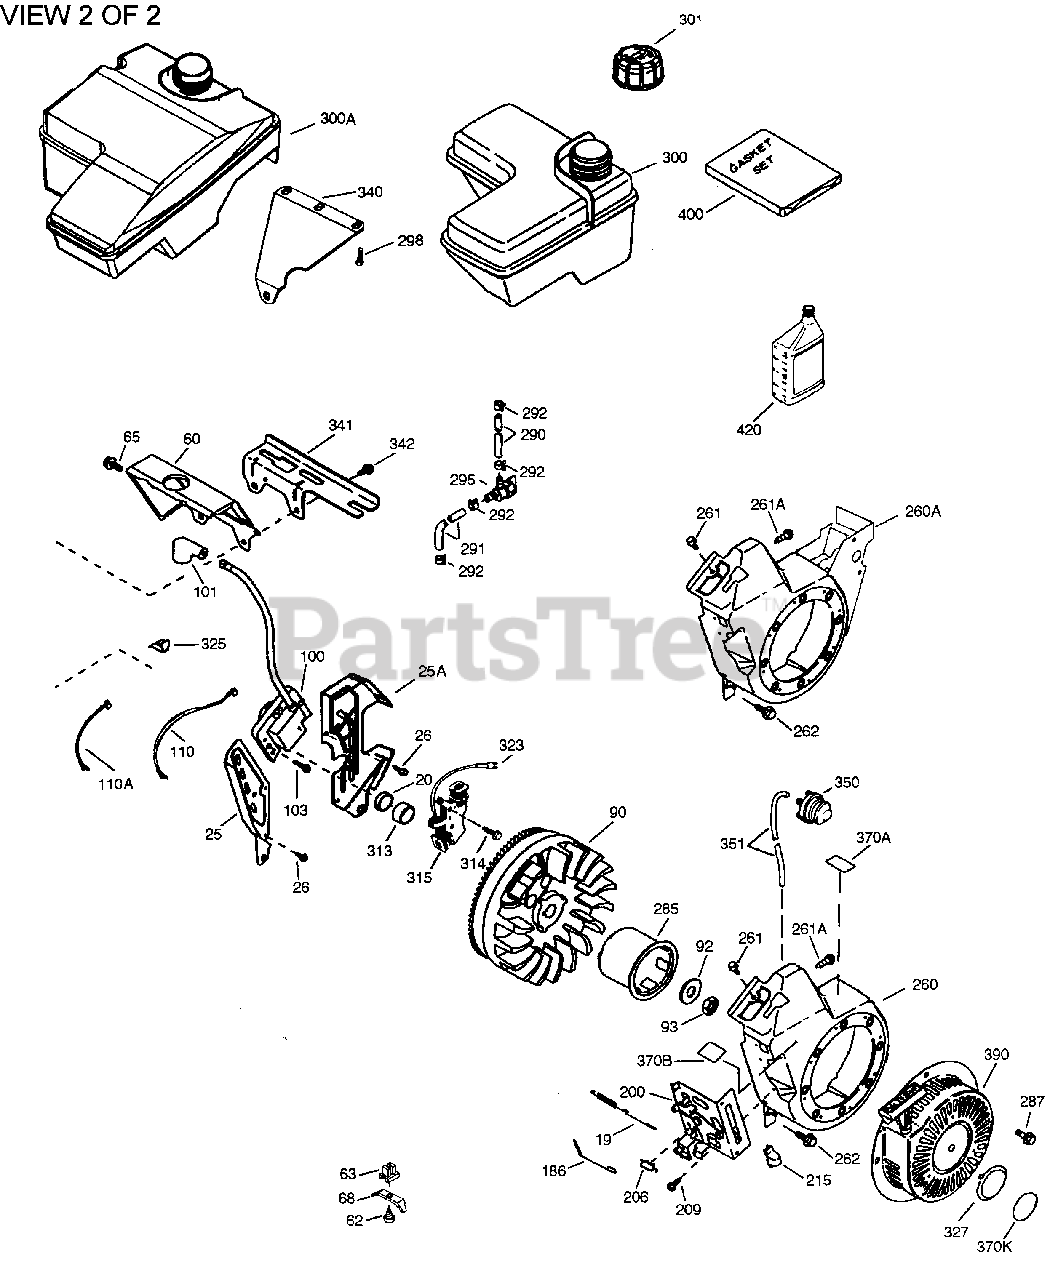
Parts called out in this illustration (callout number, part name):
19	Extension Spring
20	Oil Seal
25	Air Baffle (Left)
25A	Air Baffle (Right)
26	Screw, 10-24 x 9/16"
60	Blower Housing Extension
62	Screw, 8-32 x 3/8"
63	Breather Tube Grommet
65	Screw, 10-24 x 9/16"
68	Ground Terminal
90	Flywheel
92	Belleville Washer
93	Flywheel Nut
100	Solid State Ignition
101	Spark Plug Cover
103	Screw, Torx T-15, 10-24 x 15/16"
110	Ground Wire
110A	Ground Wire
186	Governor Link
200	Control Bracket (Incl. 206)
206	Terminal
209	Screw, 10-32 x 1/2"
215	Control Knob
260	Blower Housing
261	Screw, 1/4-20 x 31/64"
261A	Screw, 10-32 x 1/2"
262	Screw, 1/4-20 x 31/64"
281	Starter Bubble Cover
282	Screw, 6-32 x 25/64"
285	Starter Cup
287	Screw, 1/4-20 x 31/64"
290	Fuel Line
292	Fuel Line Clamp
298	Screw, 1/4-15 x 3/4"
300	Fuel Tank (Incl. 292 & 301)
301	Fuel Cap (Red)
325	Wire Clip
340	Fuel Tank Bracket (Upper)
341	Fuel Tank Bracket (Lower)
342	Screw, 1/4-20 x 7/8"
342A	Screw, 1/4-20 x 5/8"
350	Primer Assembly
351	Primer Line
355	Starter Handle (Mitten Grip) also ava ilable in Packaged Part #740053B
370A	Lubrication Decal
370B	Control Decal
370K	Starter Decal
390	Rewind Starter
400	* Gasket Set (Incl. items marked PK in notes) Incl. (1) each of 26756,27272A , 29673, 35626, 36581, 36624,36719
999	Winter Maintenance Kit incl. 5W30 Oil , Spark Plug, Key & Ultra-Fresh
999	Winter Maintenance Kit (incl. 0W30 Sy nthetic Oil, Spark Plug, Key & Ultra- Fresh)
